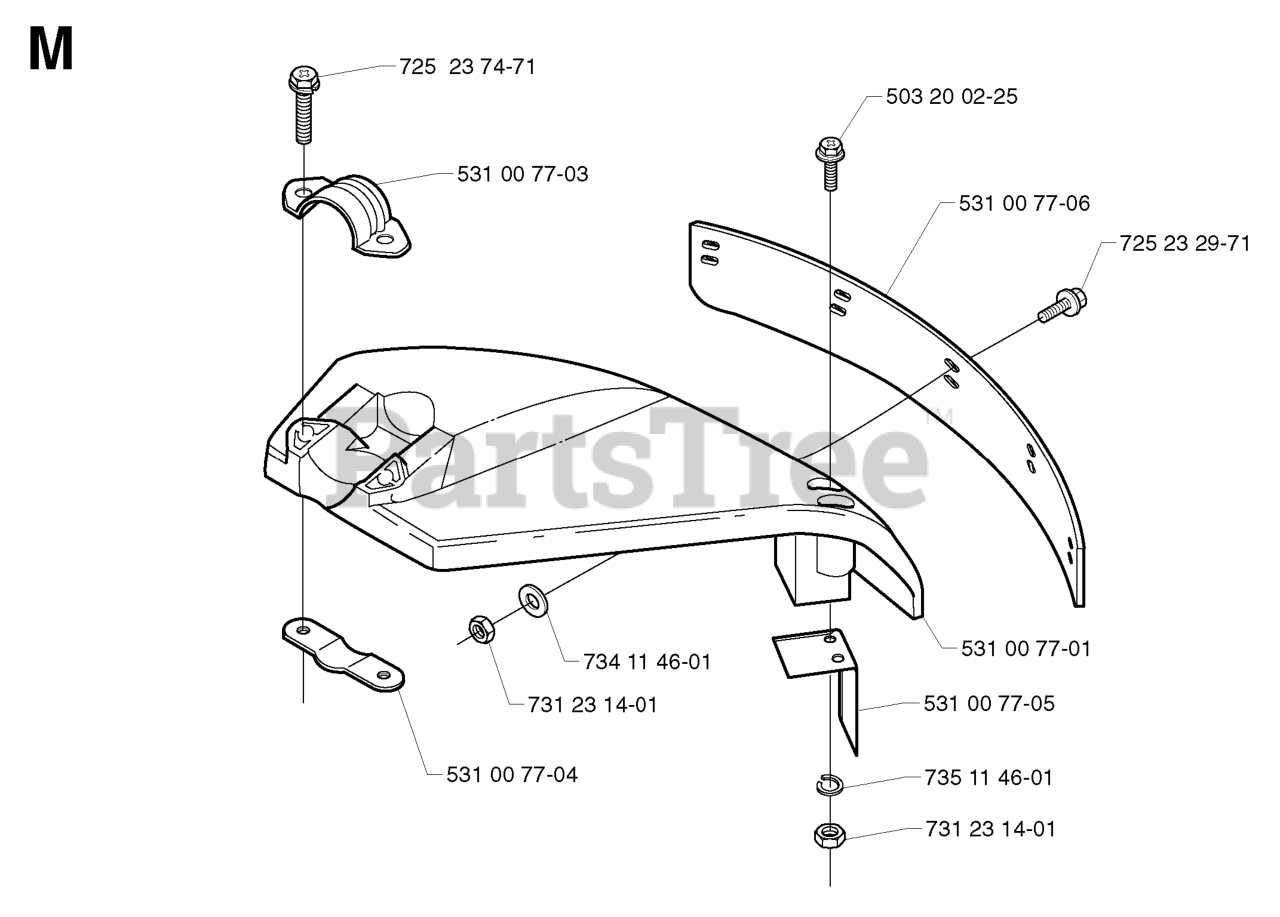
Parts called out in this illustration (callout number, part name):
1	Battery 12 Volt 25 Amp
2	BOLT.HEX.1/4.X.3/4.DICHROMATE
8	BOX.BATTERY.MOUNT.FRONT.LT
16	SWITCH INTERLOOK PUSH-IN
21	HARNESS ASSY LIGHT
24	CABLE.BATT.POS.WIRE.TG.DA SOL
25	CABLE.STARTER.6G.BL/RED.17.5
26	FUSE 20AMP
27	NUT
28	CABLE GROUND 6 GA 21" 90T BLK
29	SWITCH.SEAT.DELTA.OPC.
30	SWITCH.IGN.DELTA.W.LGH.ROS
33	KEY.CHAIN.BLISTER.PACK.GEN.USA
40	HARNESS.IGN.DASH.HUQ/P
41	SCREW
42	TERMINAL COVER
43	SOLENOID.W/BRASS.PLUNGER
46	RP.GUAGE.SRVCMNDR.HRMTR.
50	RP.PTO.SWITCH.8 TERMINAL.BLACK
55	SCREW 5/16"
71	HARNESS-CHASSIS SUB
79	BULB HOLDER ASM.
90	COVER.TERMINAL.BATTERY
91	STRAP.BATTERY.MOUNT.FRONT(2 2)
99	SCREW HEXWSHR 1/4-20X3/4
141	KIT.G700/G730.ROS 71750
